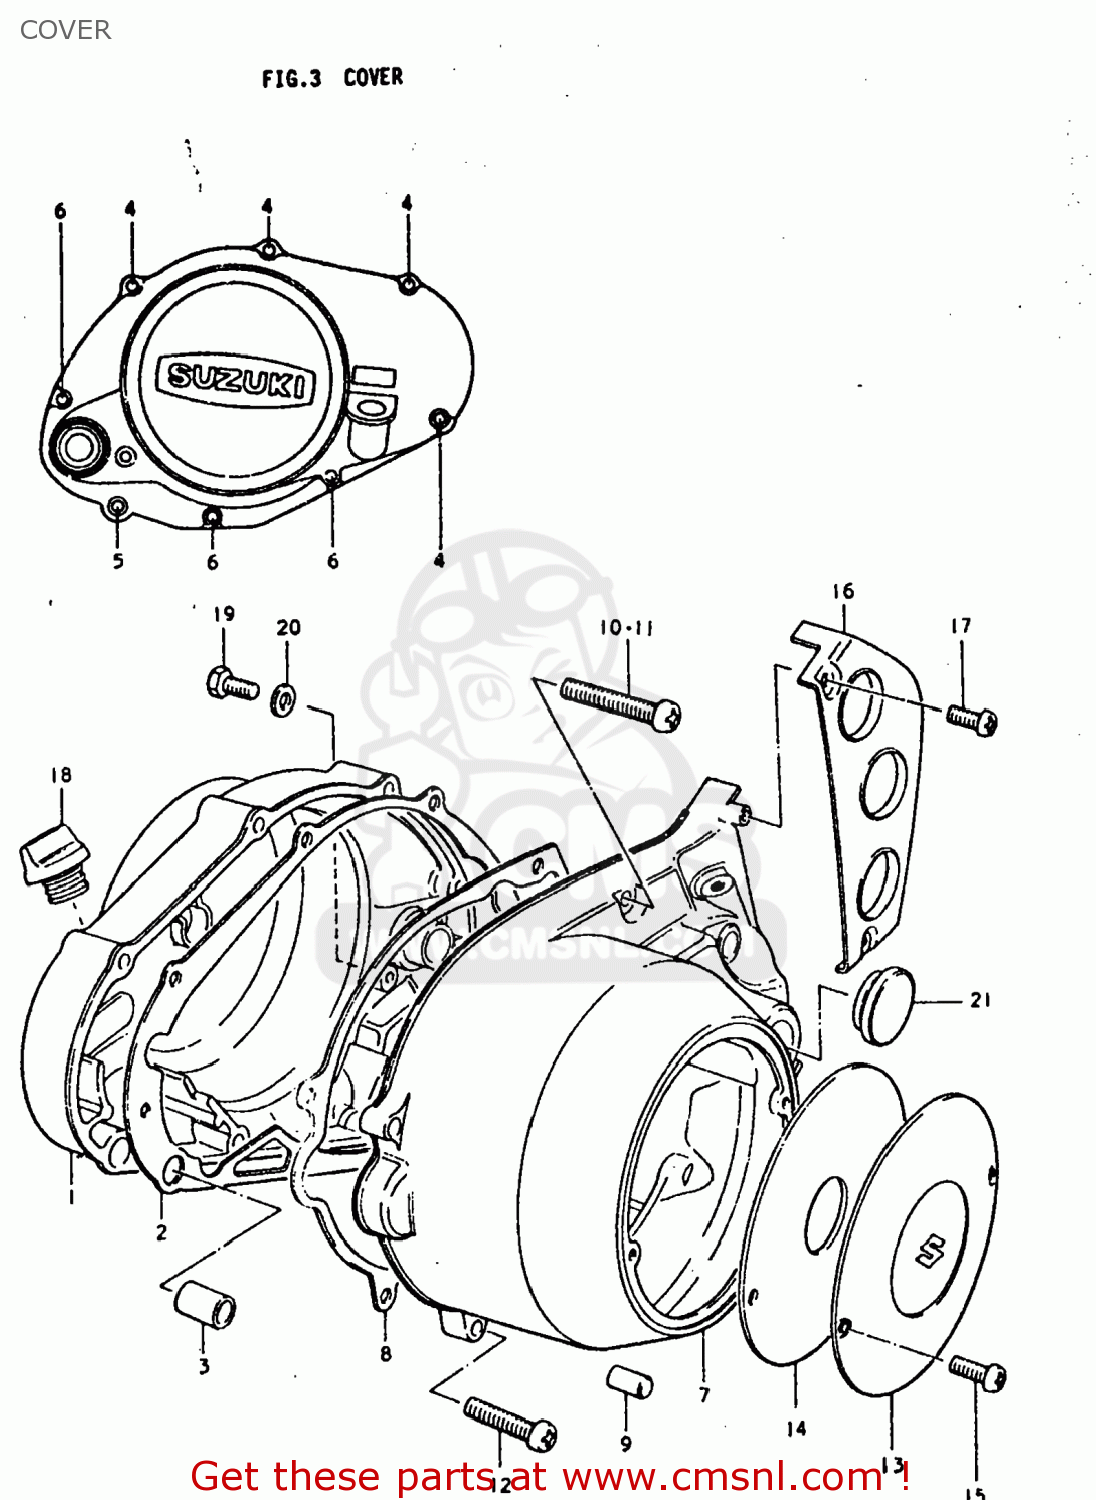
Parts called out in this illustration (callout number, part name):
1	COVER,CLUTCH
2	GASKET,CLUTCH COVER (MCA)
3	PIN
4	SCREW
5	SCREW
6	SCREW
7	COVER
8	GASKET,MAGNETO COVER (MCA)
9	PIN
10	SCREW (6X35)
11	SCREW
12	SCREW
13	CAP,MAGNETO INSPECTION
14	GASKET,MAGNETO INSPECTION (MCA)
15	SCREW
16	COVER,SPROCKET
17	SCREW
18	PLUG
19	SCREW(6X10)
20	GASKET(6.2X11X1) (NAS)
21	CAP(OD:30)
